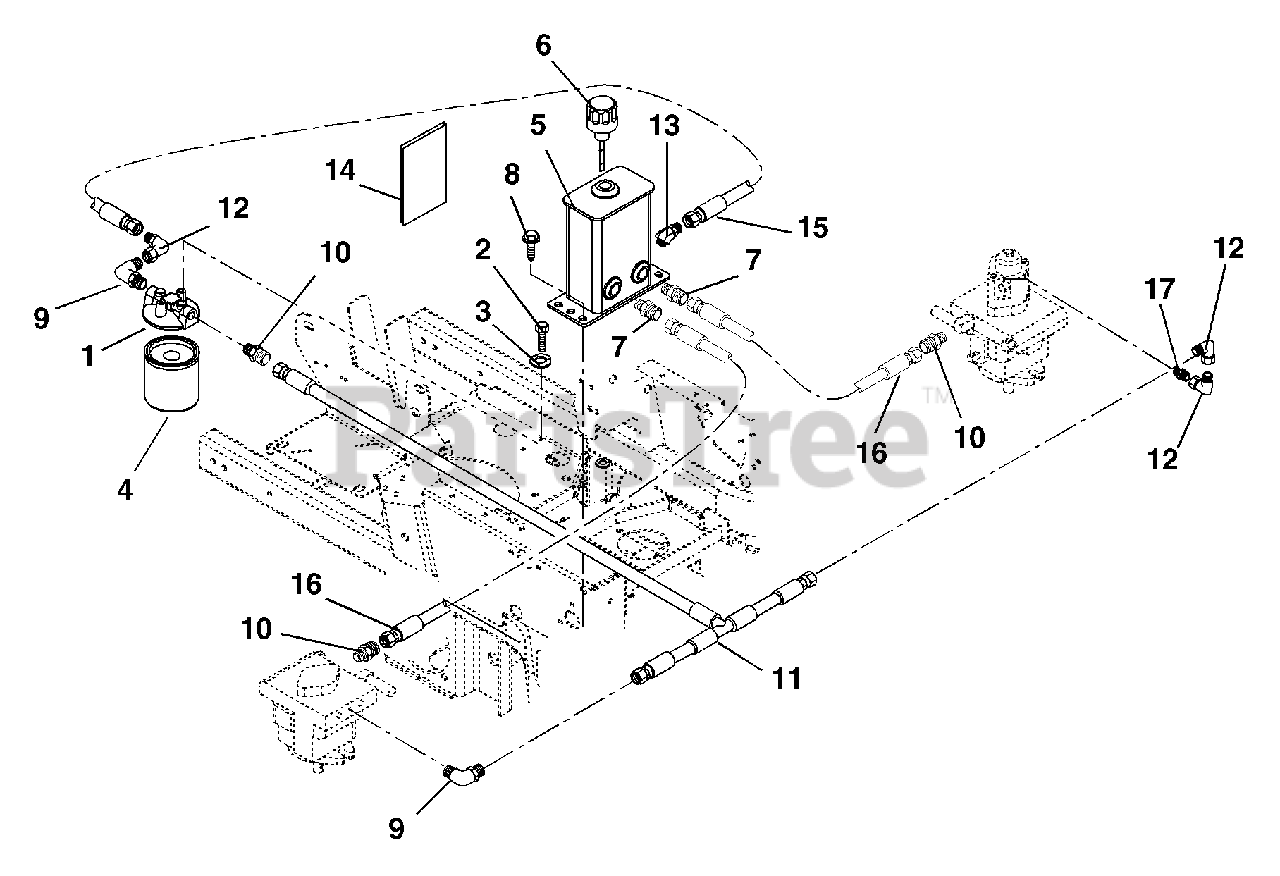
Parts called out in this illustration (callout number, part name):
1	Head, Filter
2	Bolt, Hex .25-20 x .50 Grade 5
3	Washer, Locking .25 x .062
4	Oil Filter
5	Tank, Hydraulic
6	Hydraulic Tank Dipstick
7	Adapter, Straight
8	Screw, Tapping .38-16 x .50 Hex Washer Head
9	Adapter
10	Adapter, Pipe .56-18 "O" Ring to .56-18
11	Hose, Tee Assembly .38"
12	Adapter
13	Fitting, Hydraulic 45 Degree
14	Shield, Heat 5.50 x 4.50
15	Hose,Hydraulic
16	Hose, Hydraulic
